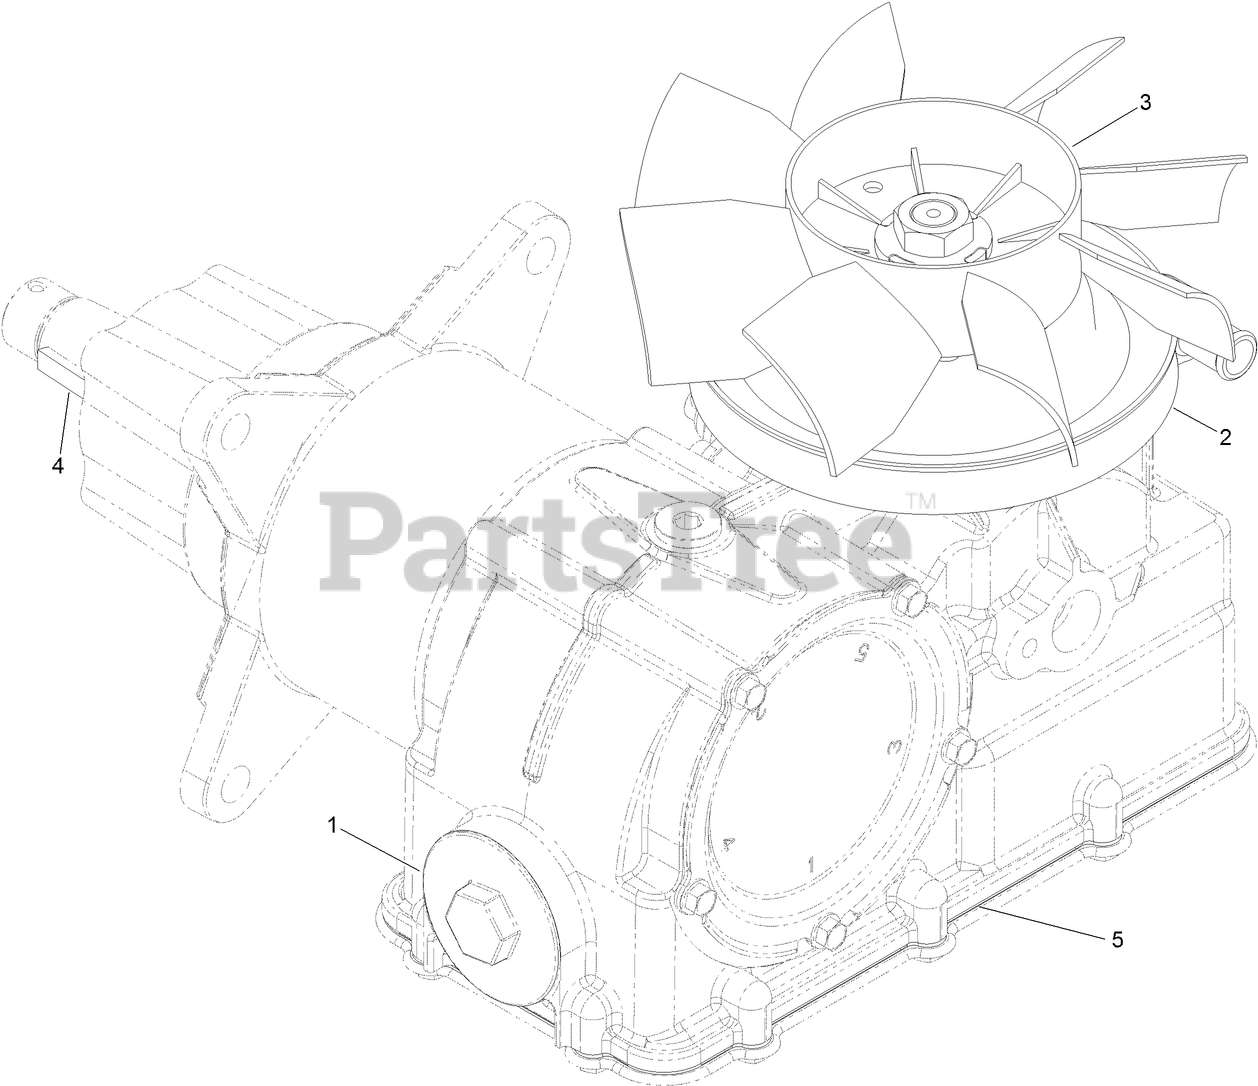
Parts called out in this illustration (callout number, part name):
1	FILTER
2	PULLEY
3	FAN (8.3 INCH)
4	KEY-WOODRUFF
5	GASKET-COVER, BOTTOM
